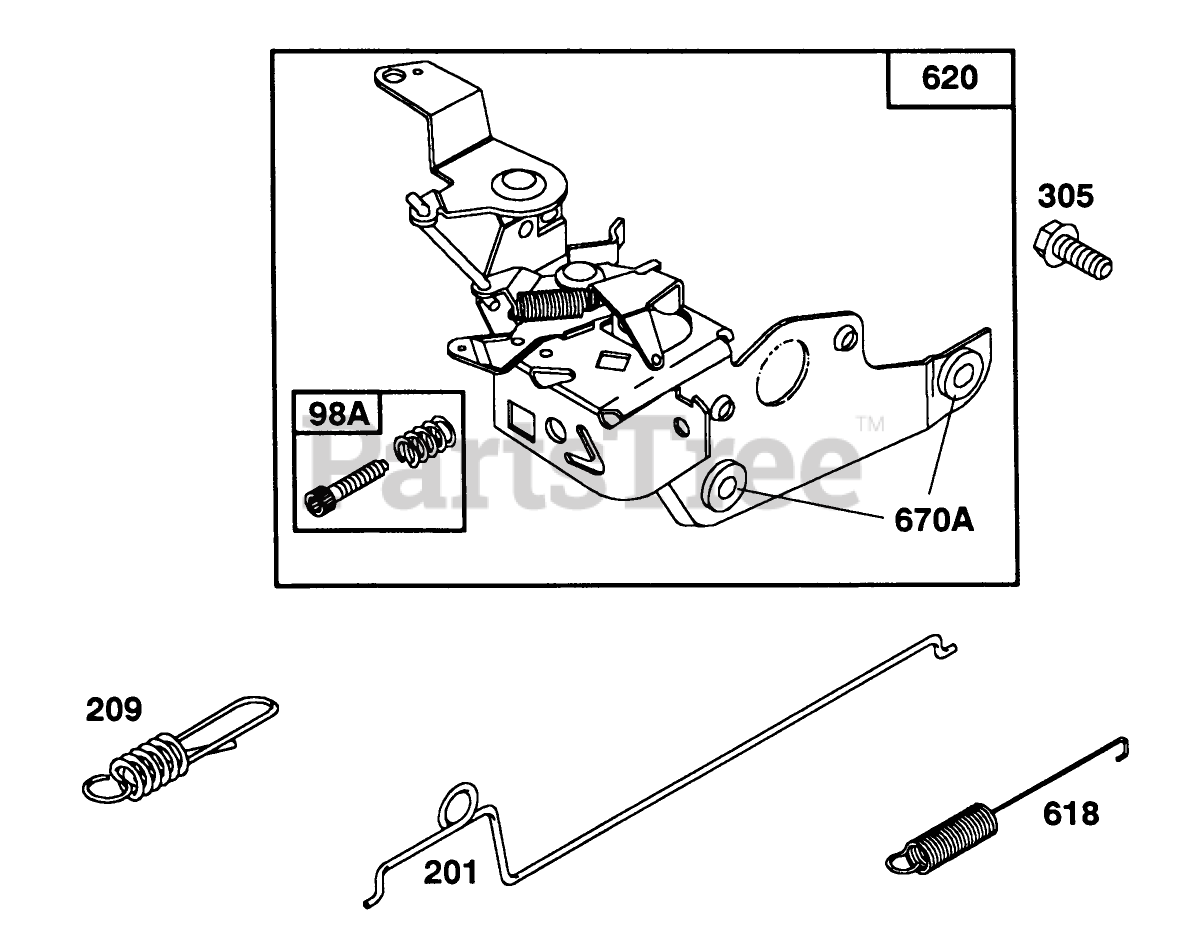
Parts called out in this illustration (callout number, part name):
98A	Screw Assy.
201	Link-Govemor
209	Spring-Govemor
305	Screw-Sem
618	Spring-Choke
620	Bracket Assembly
670A	Spacer
